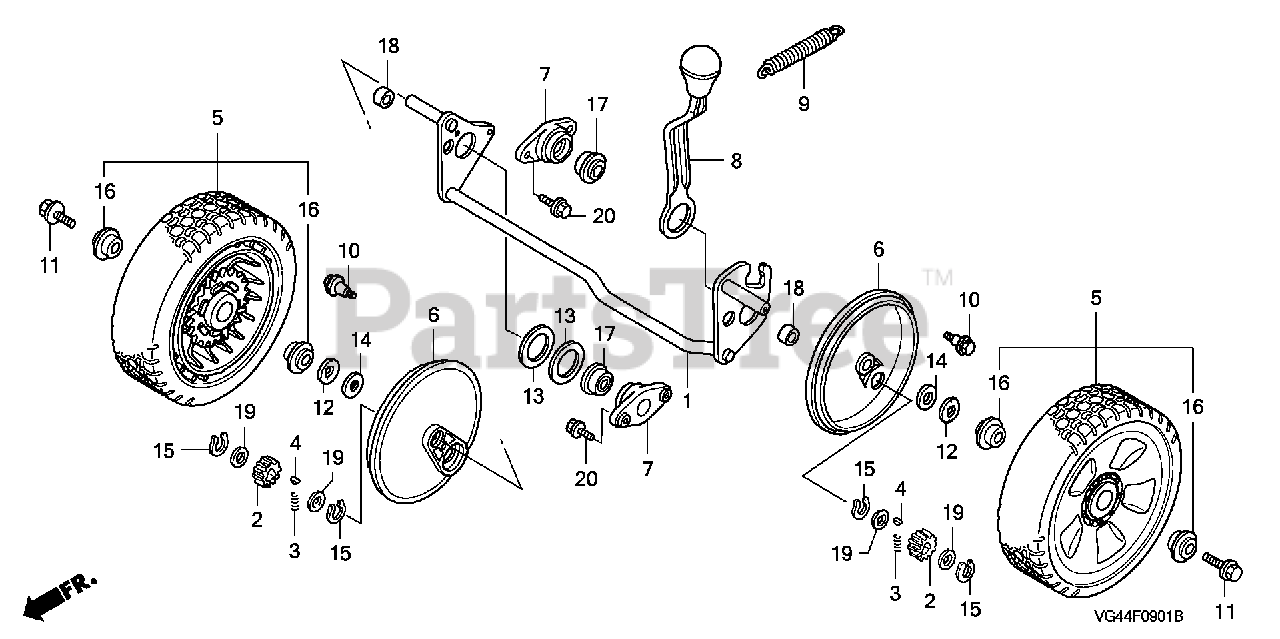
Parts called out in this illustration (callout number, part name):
1	SHAFT, RR. AXLE
2	GEAR, PINION (13T)
3	SPRING, RATCHET RETURN
4	KEY, RATCHET
5	WHEEL, RR. *NH164* (GRIP GRAY)
7	HOLDER, RR. AXLE
8	LEVER, RR. ADJUSTER *NH164* (GRIP GRAY)
9	SPRING, RR. BALANCER
10	SCREW, TAPPING (5X12)
11	BOLT, WHEEL
12	WASHER, WHEEL
13	WASHER (53MM)
14	WASHER, THRUST (13X27X1)
15	CIRCLIP (OUTER) (12.7MM)
16	BEARING, RADIAL BALL
16	BEARING, WHEEL
17	BEARING, WHEEL
18	COLLAR, THRUST
19	COLLAR, PINION GEAR
20	BOLT, FLANGE (6X14)
